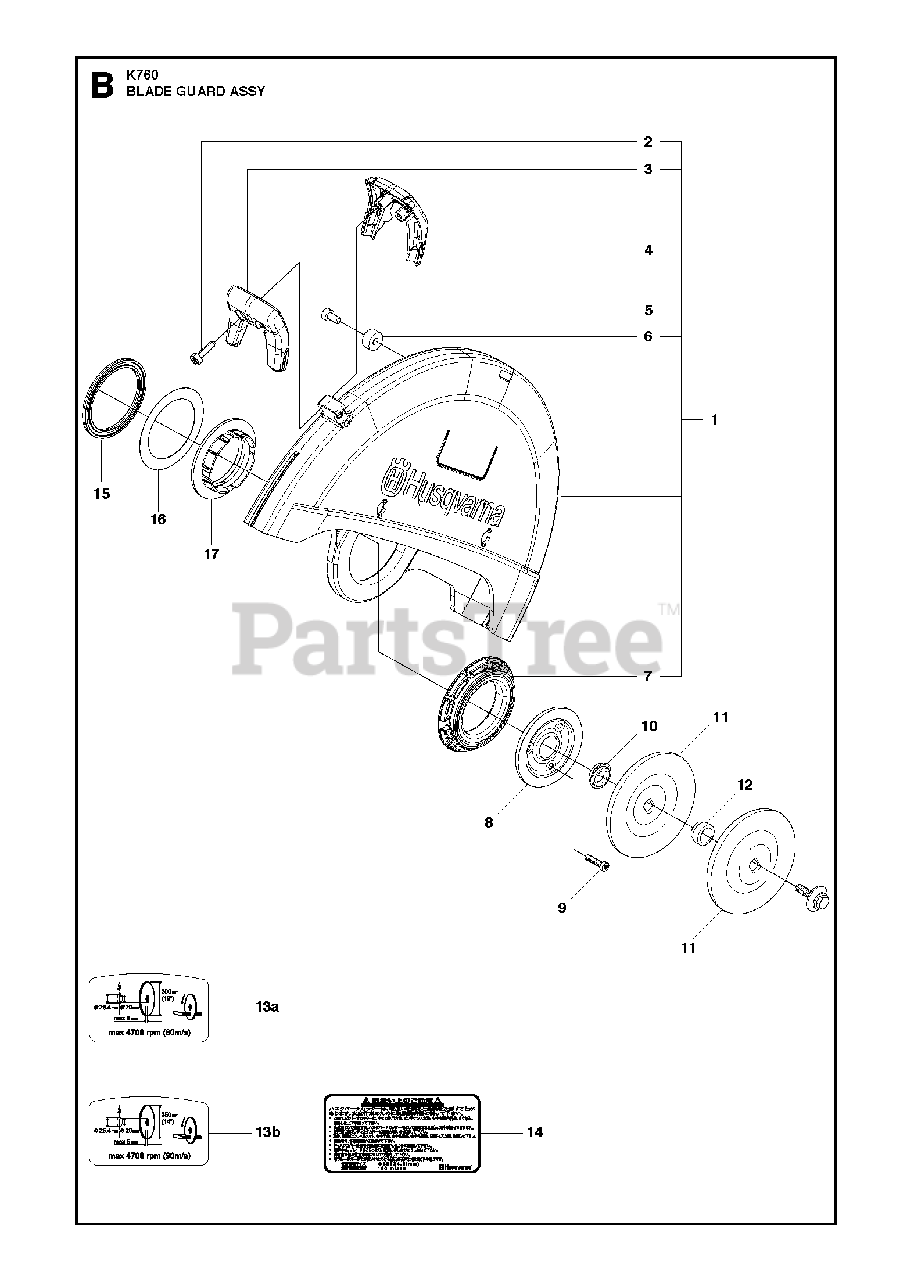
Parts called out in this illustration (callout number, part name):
1	WHEEL GUARD"12"", Incl. 2 - 7"
1	WHEEL GUARD"14"", Incl. 2 - 7"
2	SCREW ITXSCT
5	SCREW ITXSCT
9	SCREW ITXSCM
10	SUPPORT FLANGE
11	FLANGEM10, Diam 105 mm
11	FLANGE WASHERM8, UK only
11	FLANGE WASHER"Diam 119 mm, Japan 14"" only "
12	BUSHINGDiam 20 / 25,4 mm
12	BUSHINGDiam 30,5 mm
12	KITDiam 22,2 mm
14	DECAL"Japan only 12"""
14	DECAL"Japan only 14"""
